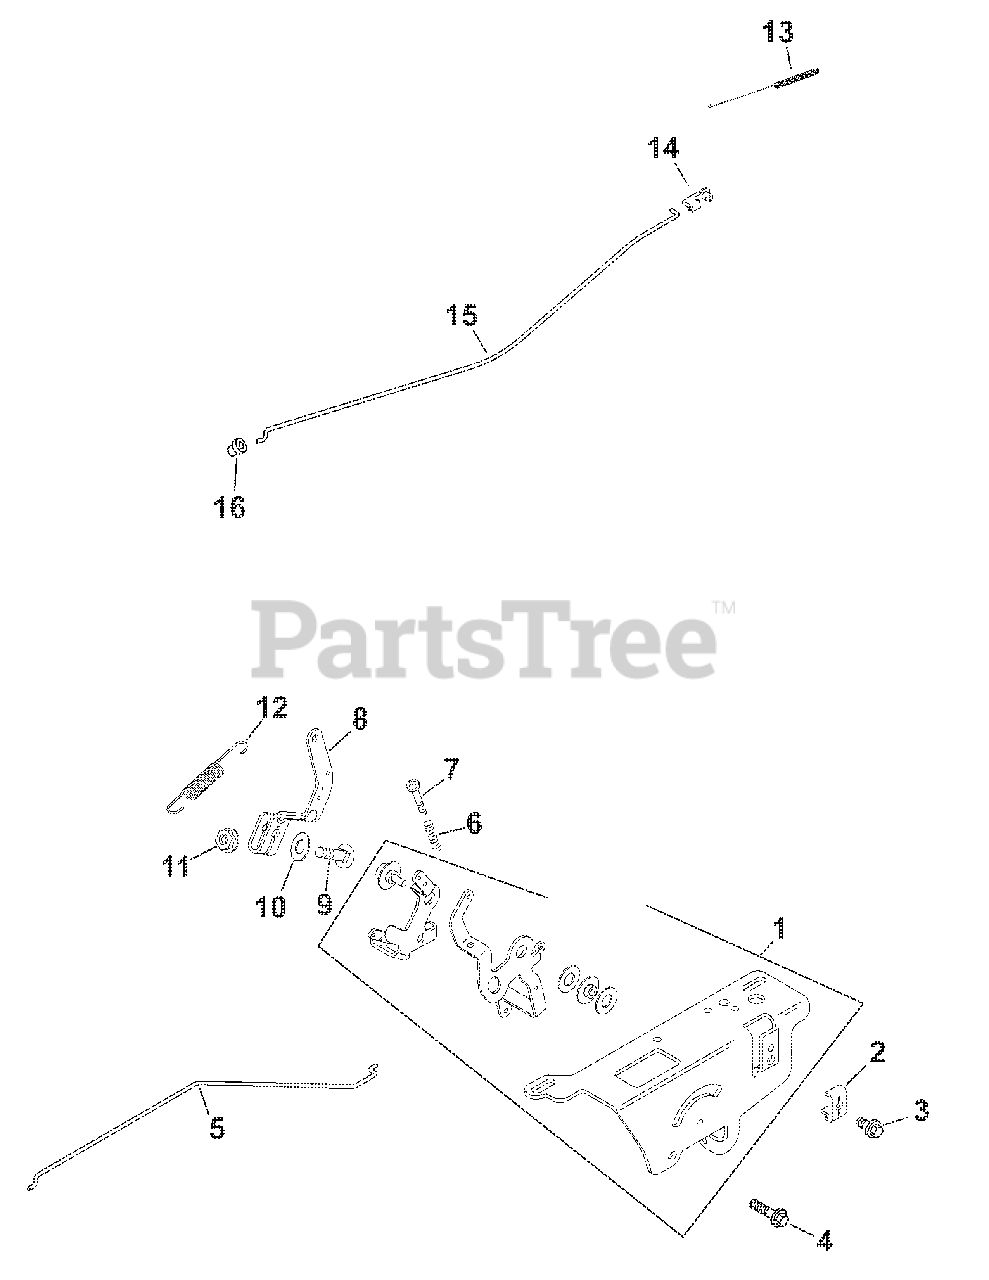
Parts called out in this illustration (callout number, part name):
1	Speed Control Assembly
2	Cable Clamp
3	Torx Head Screw
4	Lobed Socket Screw
5	Choke Linkage (Single Wire)
6	Speed Control Spring
7	Thread Forming Screw
8	Governor Lever
9	Round Head Bolt
10	1/4" Lock Washer
11	Hex Flange Nut
12	Governor Spring
13	Linkage Spring
14	Throttle Linkage Bushing
15	Throttle Linkage
16	Linkage Retaining Bushing
